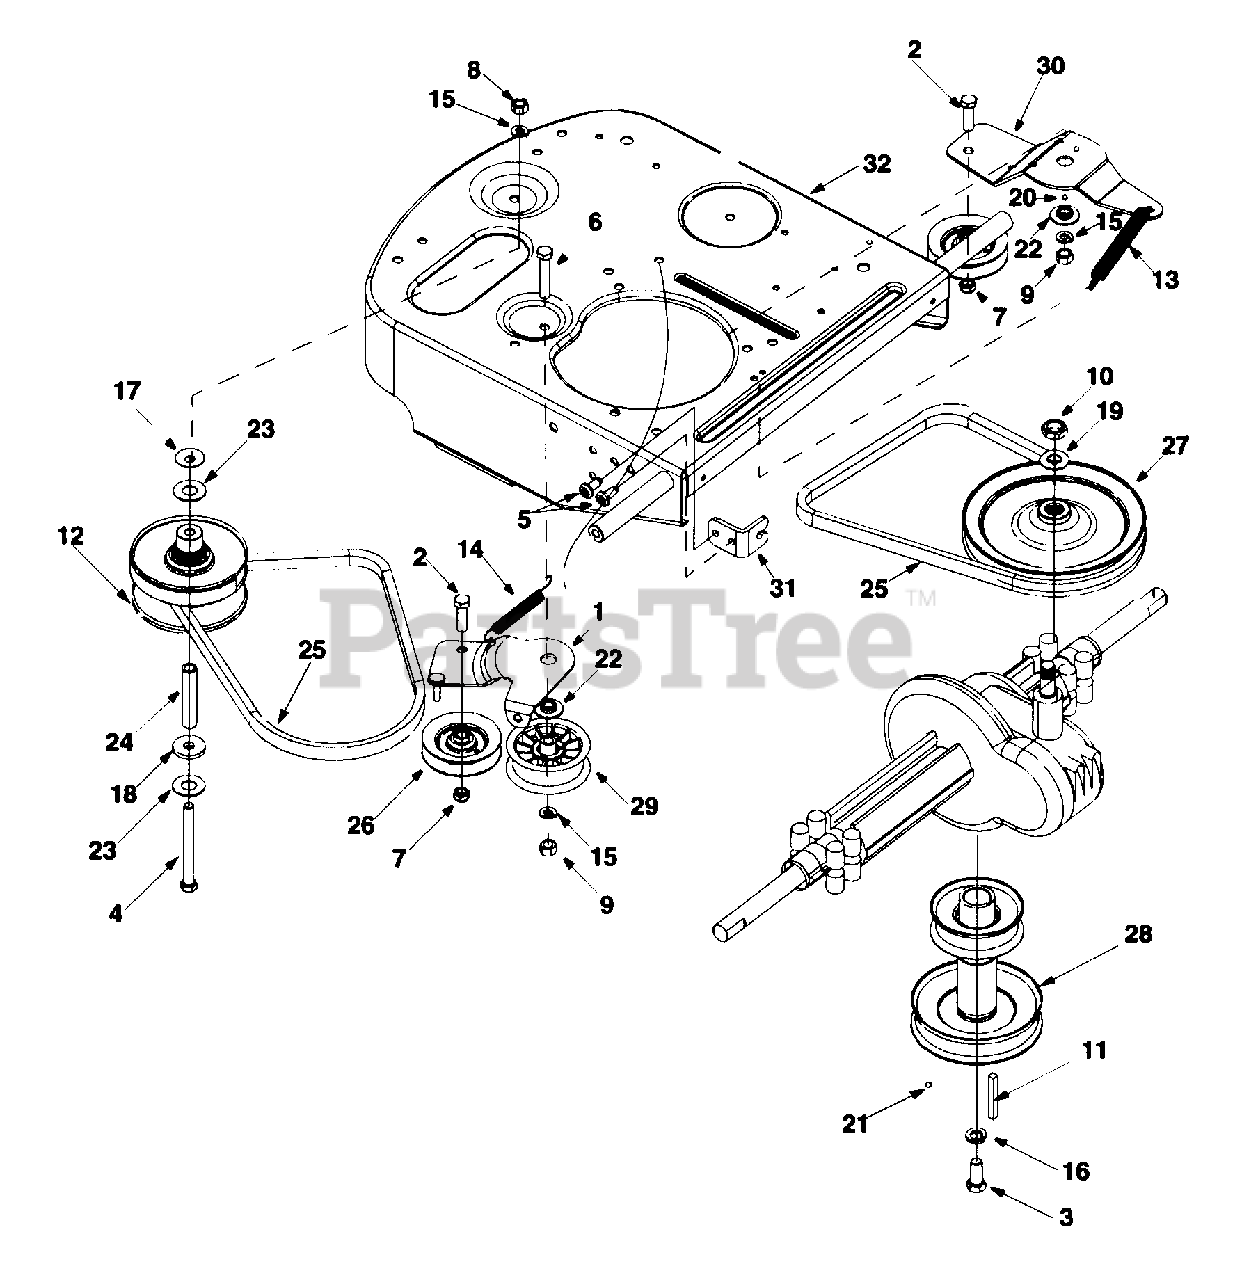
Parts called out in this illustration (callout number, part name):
1	Idler Bracket Assembly
2	Hex Screw 3/8-24 x 1.25
3	Hex Screw 7/16-20 x 1.0"
4	Cap Screw 3/8-24 x 3.75
5	Pan Head TL Screw 5/16-18 x .75
6	Hex Screw 3/8-16 x 2.0
7	Jam Lock Nut 3/8-24
8	Hex Nut 3/8-24
9	Hex Nut 3/8-16
10	Hex Jam Nut 9/16-18 (Gr. 5)
11	Square Key
12	Variable Speed Pulley Assembly
13	Extension Spring
14	Extension Spring
15	Lock Washer
16	Lock Washer 7/16 I.D.
17	Bell Washer .406 I.D. x 1.13 O.D.
18	Flat Washer 3/8 x 1.25 O.D.
19	Belleville Washer
22	Shoulder Spacer
23	Bearing
25	V-Belt
26	Idler Pulley
27	Transmission Pulley
28	Engine Pulley
29	Flat Idler Pulley
30	Idler Bracket
31	Cable Bracket
32	Frame: Lower, Yellow
